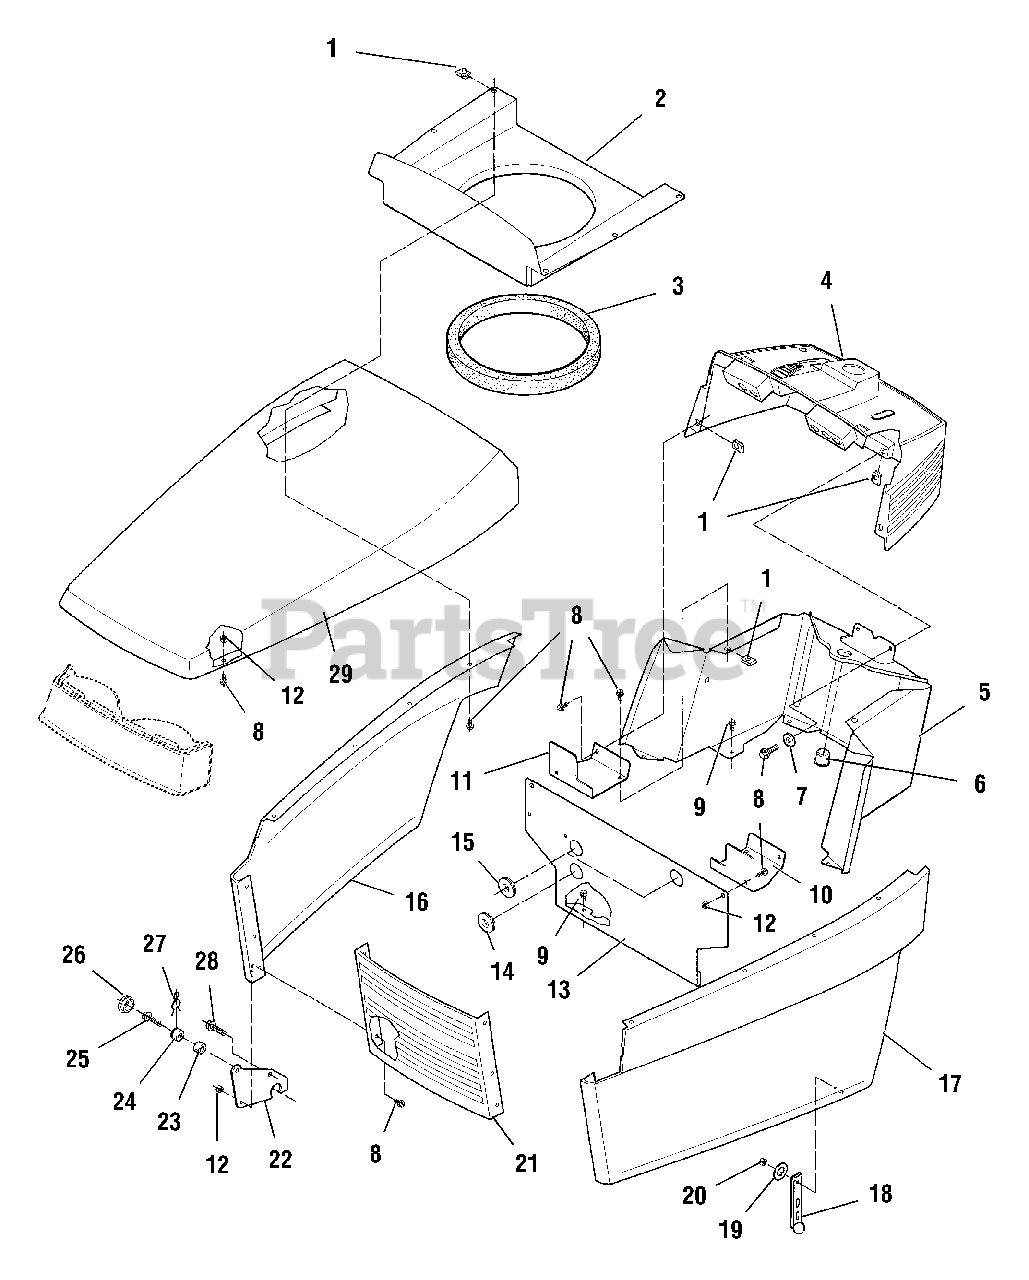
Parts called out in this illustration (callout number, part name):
1	PAL NUT, 1/4-20
3	SEAL, Air Duct
5	DASH, Lower
6	BUSHING, Nylon
7	WASHER, Plain, 1/4
8	CAPSCREW, Whizlock, 1/4-20 x 5/8
9	SCREW, Taptite, 1/4-20 x 1/2
10	SUPPORT, Bulkhead, LH
11	SUPPORT, Bulkhead, RH
12	NUT, Hex, Full Lock, 1/4-20
13	BULKHEAD
14	GROMMET, Wire Harness
15	GROMMET, Bulkhead
16	SIDE PANEL ASSY., RH, Orange
16	SIDE PANEL ASSY., RH, Red
17	SIDE PANEL ASSY., LH, Orange
17	SIDE PANEL ASSY., LH, Red
18	STRAP, Hood
19	WASHER, Special
20	NUT, Hex, Lock, Nylon #10-24
21	GRILLE
22	HINGE, Hood
24	PIVOT, Hood
25	SCREW, Taptite, 5/16-18 x 1
26	SPACER, Hood
27	CLIP, Hairpin
28	SCREW, Taptite, 5/16-18 x 5/8
29	HOOD, Orange
29	HOOD, Red
